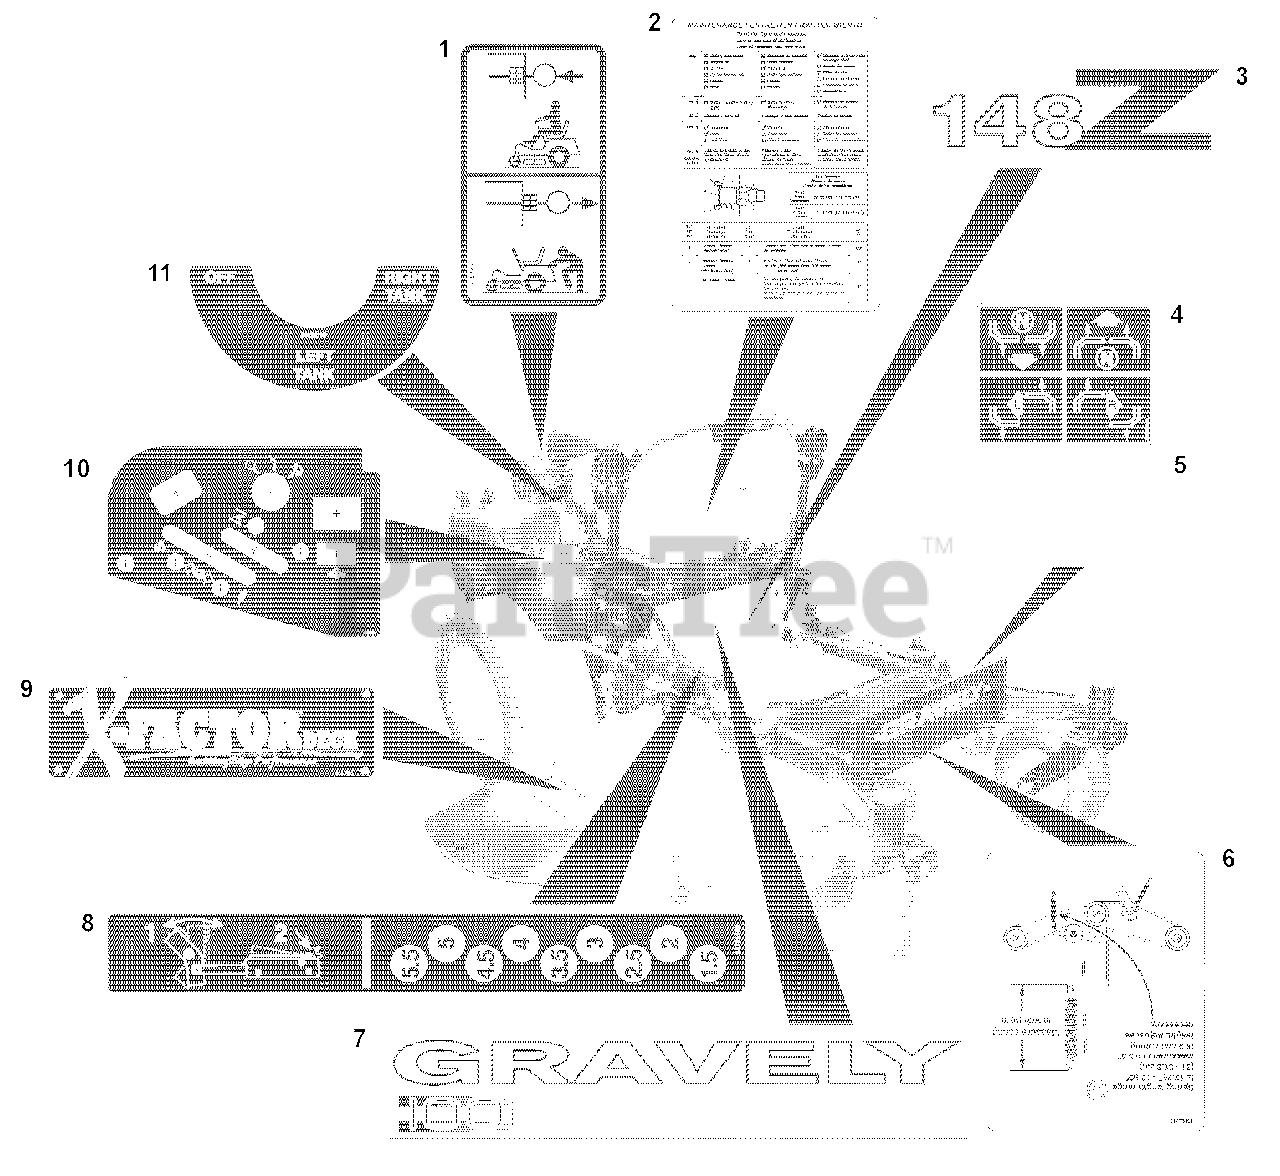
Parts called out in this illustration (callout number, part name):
1	DECAL, TRANSMISSION DISCONNECT
2	DECAL-MAINTENANCE INSTRUCTIONS
3	DECAL, LOGO - GRAVELY 148Z
4	DECAL, INSTRUCTIONAL-STEERING
5	DECAL, AMERICAN FLAG
6	DECAL, BELT ROUTING
7	DECAL, 100I
8	DECAL, HEIGHT OF CUT
9	DECAL, X-FACTOR DECK
10	DECAL CONTROL PANEL
11	DECAL, FUEL VALVE
